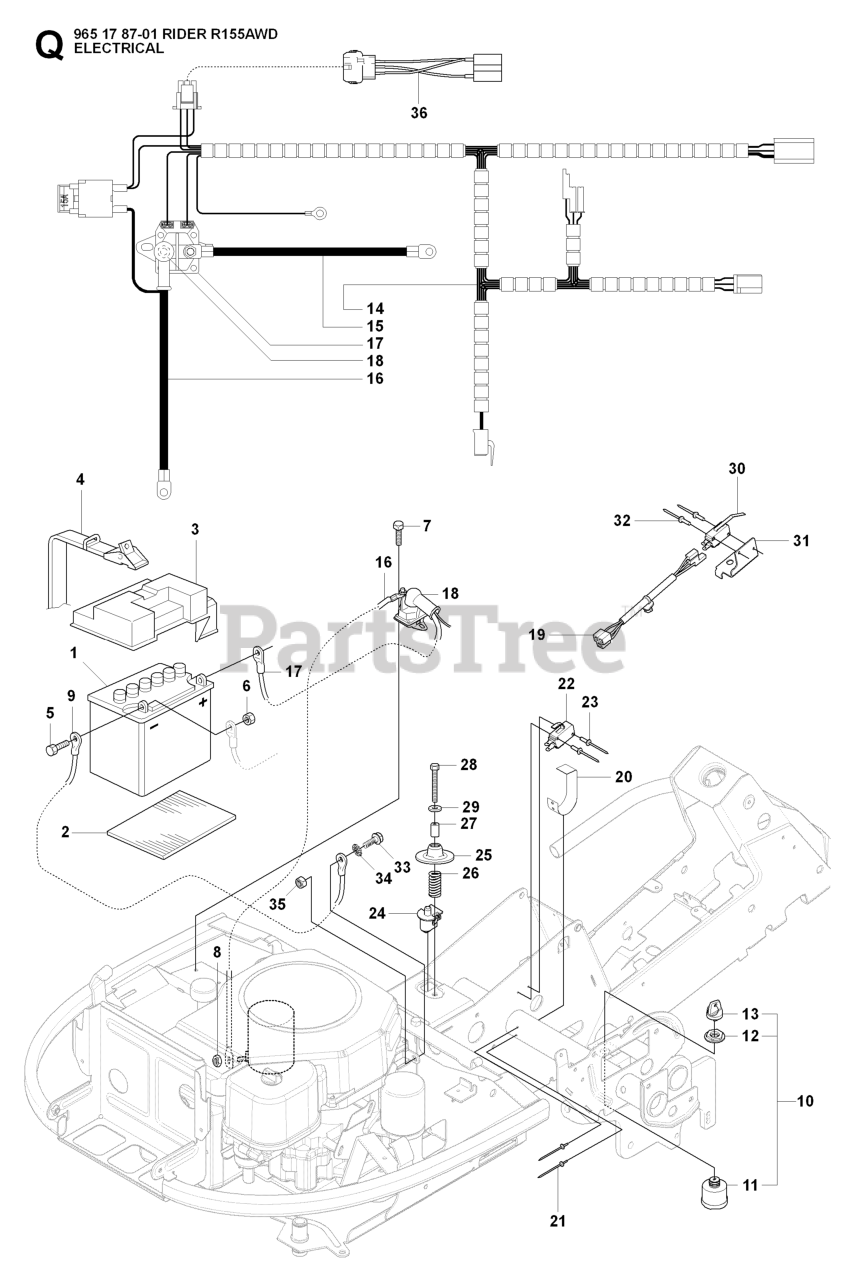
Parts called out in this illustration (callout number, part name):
1	BATTERY - DRY
10	IGNITION SWITCH
11	IGNITION SWITCH
13	IGNITION KEY
19	WIRING
22	%BRAKER
27	SPACER TUBE
28	SCREW
29	WASHER BRB 8.4X17
30	RP MICRO SWITCH
35	NUT
